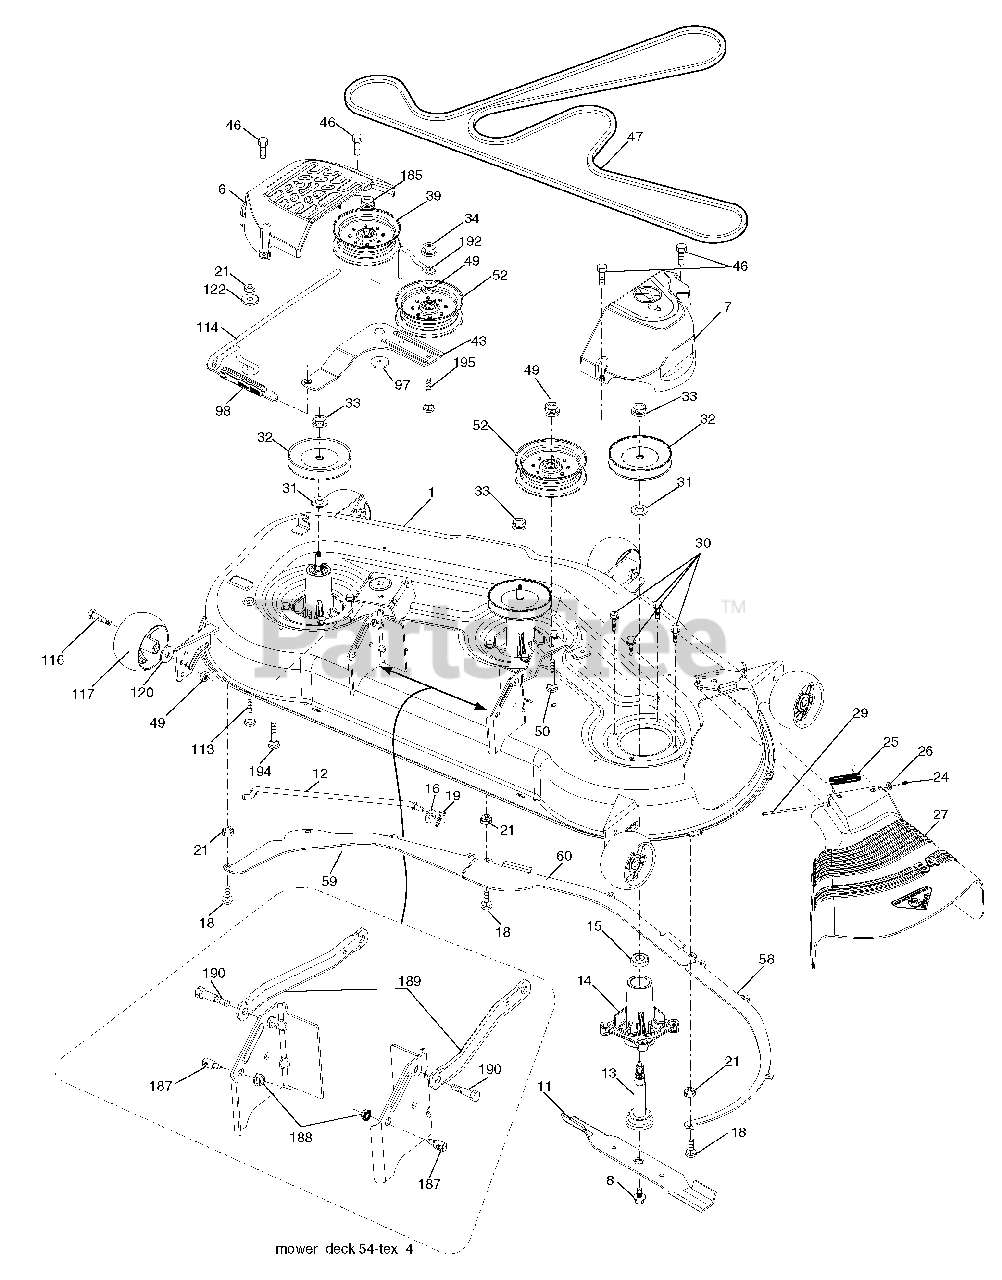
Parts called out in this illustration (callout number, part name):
1	Deck Weldment Mower
6	Cover Mandrel LH
7	Cover Mandrel RH
8	Bolt 7/16 Asm. Blade
8	Blade Mulching
11	Blade Bagging
12	Rod Anti-Sway
13	Shaft Asm. w/Lower Bearing
14	Housing, Mandrel
15	Bearing, Ball, Mandrel
16	Washer 13/32 x 13/16 x 12 Ga.
17	Bolt Carr. 5/16-18 x 5/8
18	Bolt RDHD SQNK 5/16-18 x 5/8
19	Pin Cotter 5/16 Bow Tie Lock
21	Nut, Crownlock 5/16-18 unc
24	Cap Sleeve
25	Spring, Torsion
26	Nut, Push
27	Defl ector Shield
29	Rod, Hinge
30	Screw, Thdroll Washer Head
31	Washer, Spacer Mower Vented
32	Pulley, Mandrel
33	Nut, Flg. Top Lock
34	Nut Crownlock 3/8-16 unc
39	Pulley, Idler, Stationary
43	Arm, Idler
46	Screw, Thdroll. 1/4-20 x 5/8
47	V-Belt, Mower
49	Nut, Lock Flg. 3/8-16 unc
50	Bolt Rdhd Sqnk 3/8-16 unc x 2
52	Pulley Idler Clutching
58	Baffl e Right
59	Baffl e Left
60	Baffl e Center
97	Washer Hardened
98	Spring Drive
113	Bolt Rdhd Sqnk 5/16-18 x 3/4
114	Rod Tension Relief
116	Bolt, Shoulder
117	Gauge Wheel
120	Washer 13/32 x 1-1/4 x 12 Ga.
122	Bushing Tension Relief
185	Nut Lock Flange 7/16-14 Gr. 5
187	Stud Fastener w/"D" Anti-Rotation
188	Nut Lock Hex Flange 5/16-18
189	Arm Susp. Mower Rear
190	Bolt Shoulder
192	Keeper Belt Idler
194	Bolt Carr Sqnk 3/8-16 x 2-1/4
195	Bolt Rdhd 3/8-16 unc x 2-1/2 Gr. 5
195	High Lift
195	Mandrel Asm. Service
195	Replacement Mower, Complete
